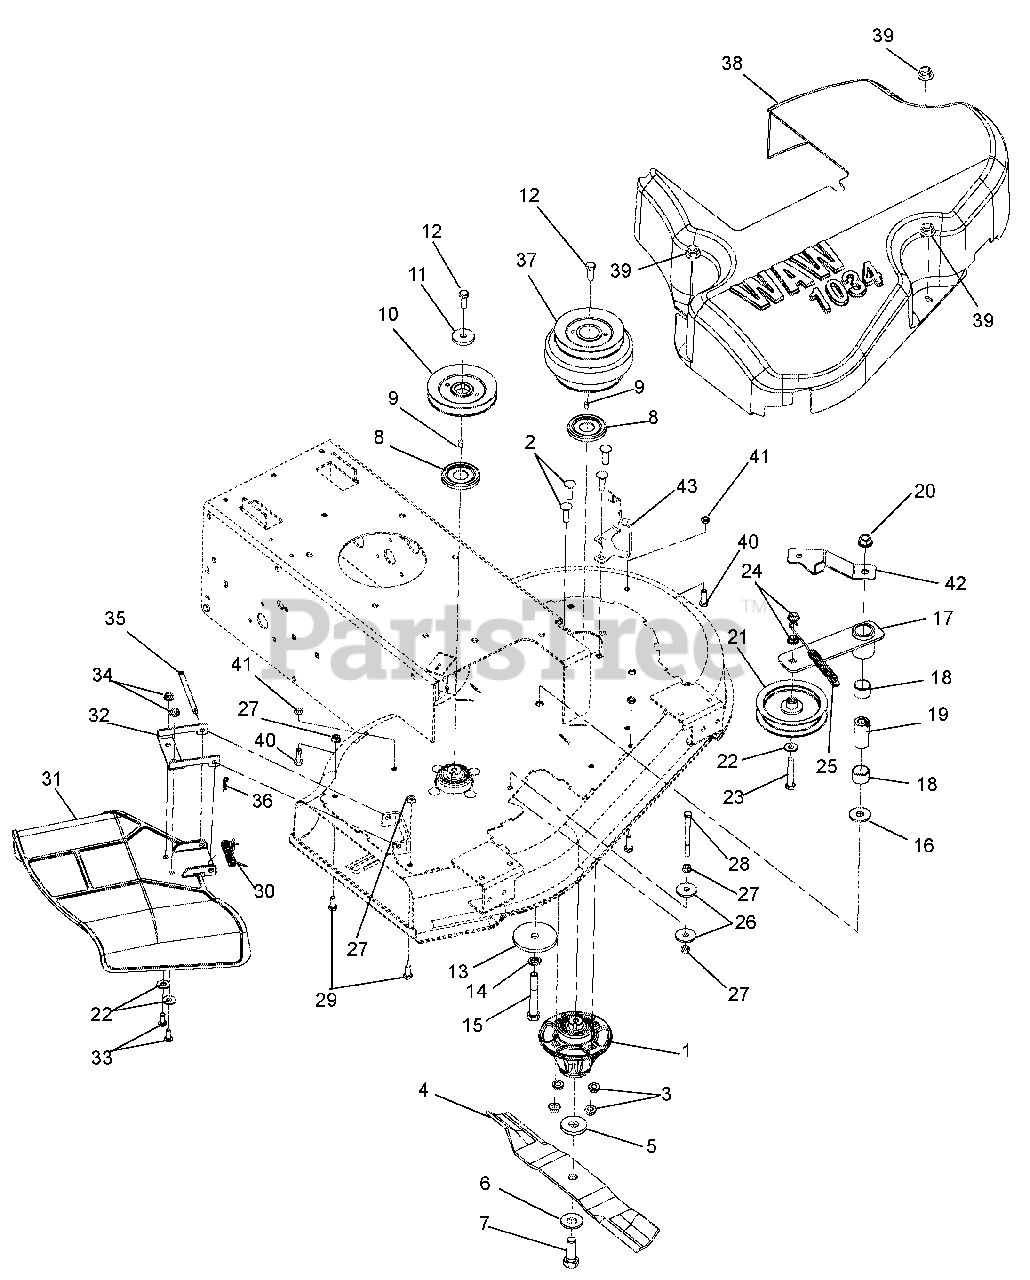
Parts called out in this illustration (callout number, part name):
1	Spindle Assembly
2	Bolt, Round Head, Square Neck .38-16 x 1.25
3	Nut .38-16 Nyloc Flange
4	Blade 17.5 x 2.25 x .197
5	Washer, Flat .640 x 1.75 x .250
6	Washer, Bellville .63 x 1.62 x .14
7	Bolt, Hex .62-18 x 1.75 Grade 8
8	Cap, Dust
9	Key, Square .25 x .38 x .25
10	Sheave 4.75 Diameter A-Section
11	Washer, Flat Steel .406 x 1.50 x .245
12	Bolt, Hex .38-16 x 1.00
13	Washer, Flat .531 x 3.00 x .25
14	Washer, Locking .50 x .125
15	Bolt, Hex .50-13 x 3.50
16	Washer, Flat Steel .511 x 1.44 x .125
17	Arm, WAW Deck Idler
18	Bearing 1.00 x 1.12 x .75
19	Bushing, Spacer .505/.500 x .999/.996 x 2.05/2.03
20	Nut, Locking Top Flange .50-13
21	Idler, Flat .38 x 4.00 x 1.06
22	Washer, Flat Steel .38 x .875 x .083
23	Bolt, Hex .38-16 x 2.25
24	Nut, Locking Flange .375-16
25	Spring, Engine-Transmission
26	Washer, Flat Steel .406 x 1.375 x .135
27	Nut, Spin Lock Flange .312-18 (403)065298001Nut, Locking Center .31-18
28	Bolt, Hex .31-18 x 3.50
29	Bolt, Hex .31-18 x .75
30	Spring, Torsion
31	Chute, Molded
32	Reinforcement, Chute
33	Screw, Socket Head .31-18 x .75 Button Head
34	Nut, Locking Top Flange .31-18
35	Pin, .3125 x 3.88
36	Pin, Internal Hair .08 x .18 x 1.18
37	Pulley, Deck Input
38	Cover, Belt
39	Nut, .31-18 Nyloc Flange
40	Bolt, Hex .31-18 x 1.00
41	Nut, Locking Center .31-18
42	Bracket, Idler Brace
43	Finger, Jackshaft Belt
